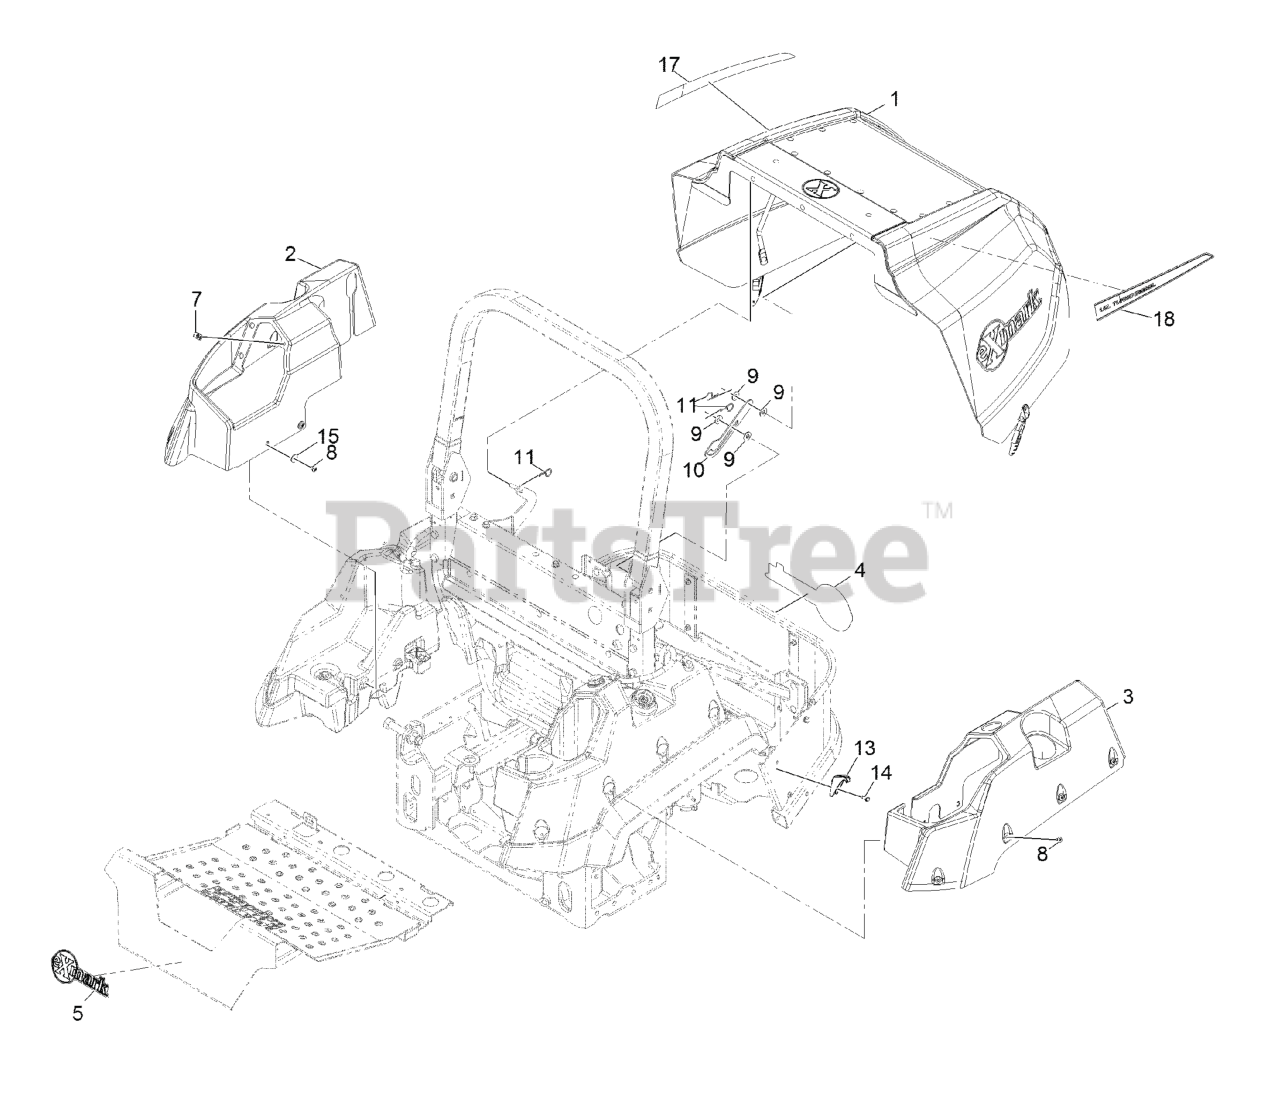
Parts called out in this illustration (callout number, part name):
1	Hood ASM
2	COVER-TANK, RH
3	COVER-TANK, LH
4	DECAL-EXMARK
5	DECAL-EXMARK
8	SCREW-TORX
9	WASHER-FLAT
10	PROP-HOOD
11	PIN-COTTER, HAIR
13	LATCH-CATCH
14	SCREW-HWH
15	WASHER-FLAT
17	DECAL-TURBO DIESEL-RH
18	DECAL-TURBO DIESEL-LH
